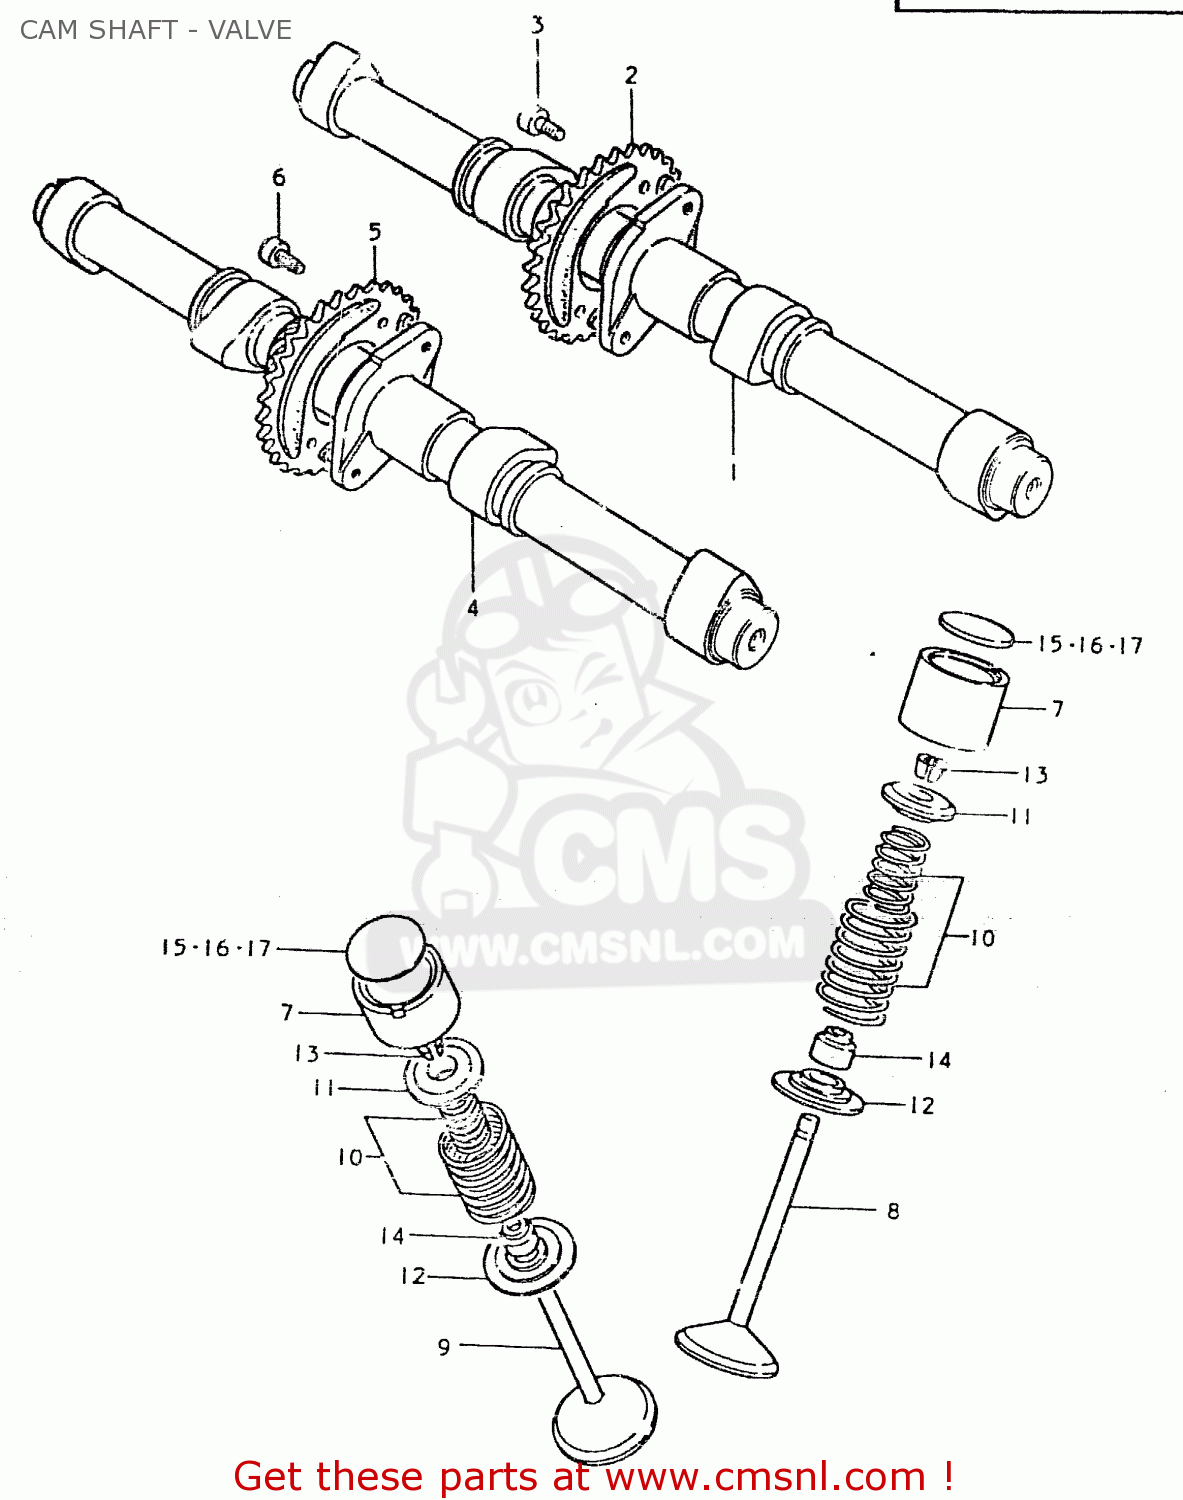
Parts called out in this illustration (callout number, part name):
1	CAMSHAFT
2	SPROCKET,CAMSHAFT
3	BOLT 6X11
4	CAMSHAFT,EXHAUST
5	SPROCKET,EXHAUST CAMSHAFT
6	BOLT 6X11
7	TAPPET
8	VALVE,INTAKE
9	VALVE,EXHAUST
10	SPRING SET,VALVE
11	RETAINER,VALVE SPRING
12	SEAT,VALVE SPRING
13	COTTER VALVE
14	SEAL,OIL(7X14.4X9)
15	SHIM,TAPPET
16	SHIM,TAPPET
17	SHIM,TAPPET
